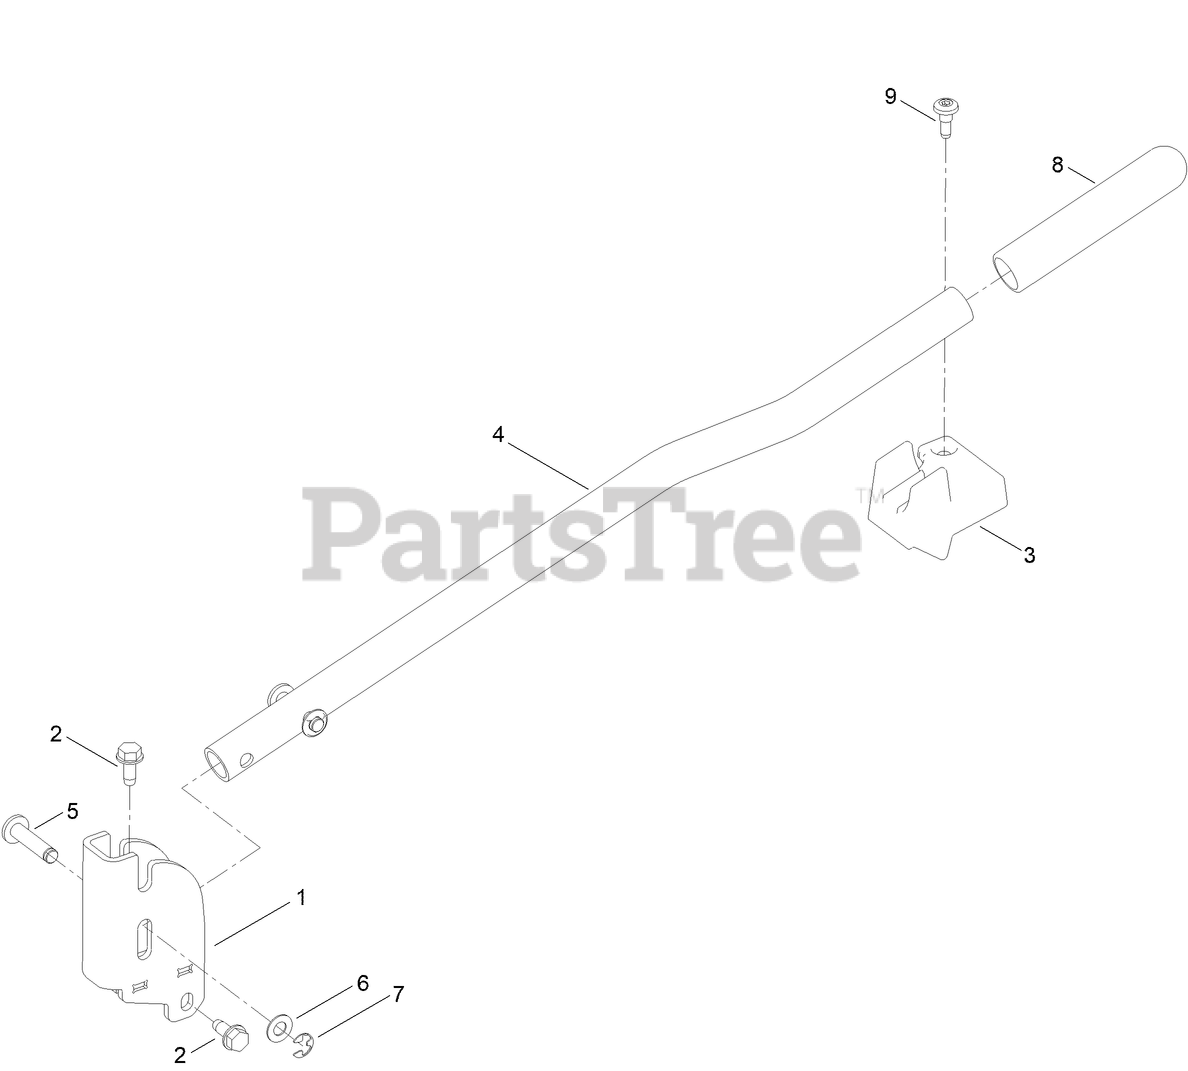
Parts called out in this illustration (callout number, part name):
1	WA-ASSIST BRACKET
2	SCREW-HWHTF
3	RETAINER-HANDLE
4	TUBE-ASSIST
5	PIN-ASSIST HANDLE
6	WASHER-THRUST
7	E-RING
9	SCREW-SHOULDER
